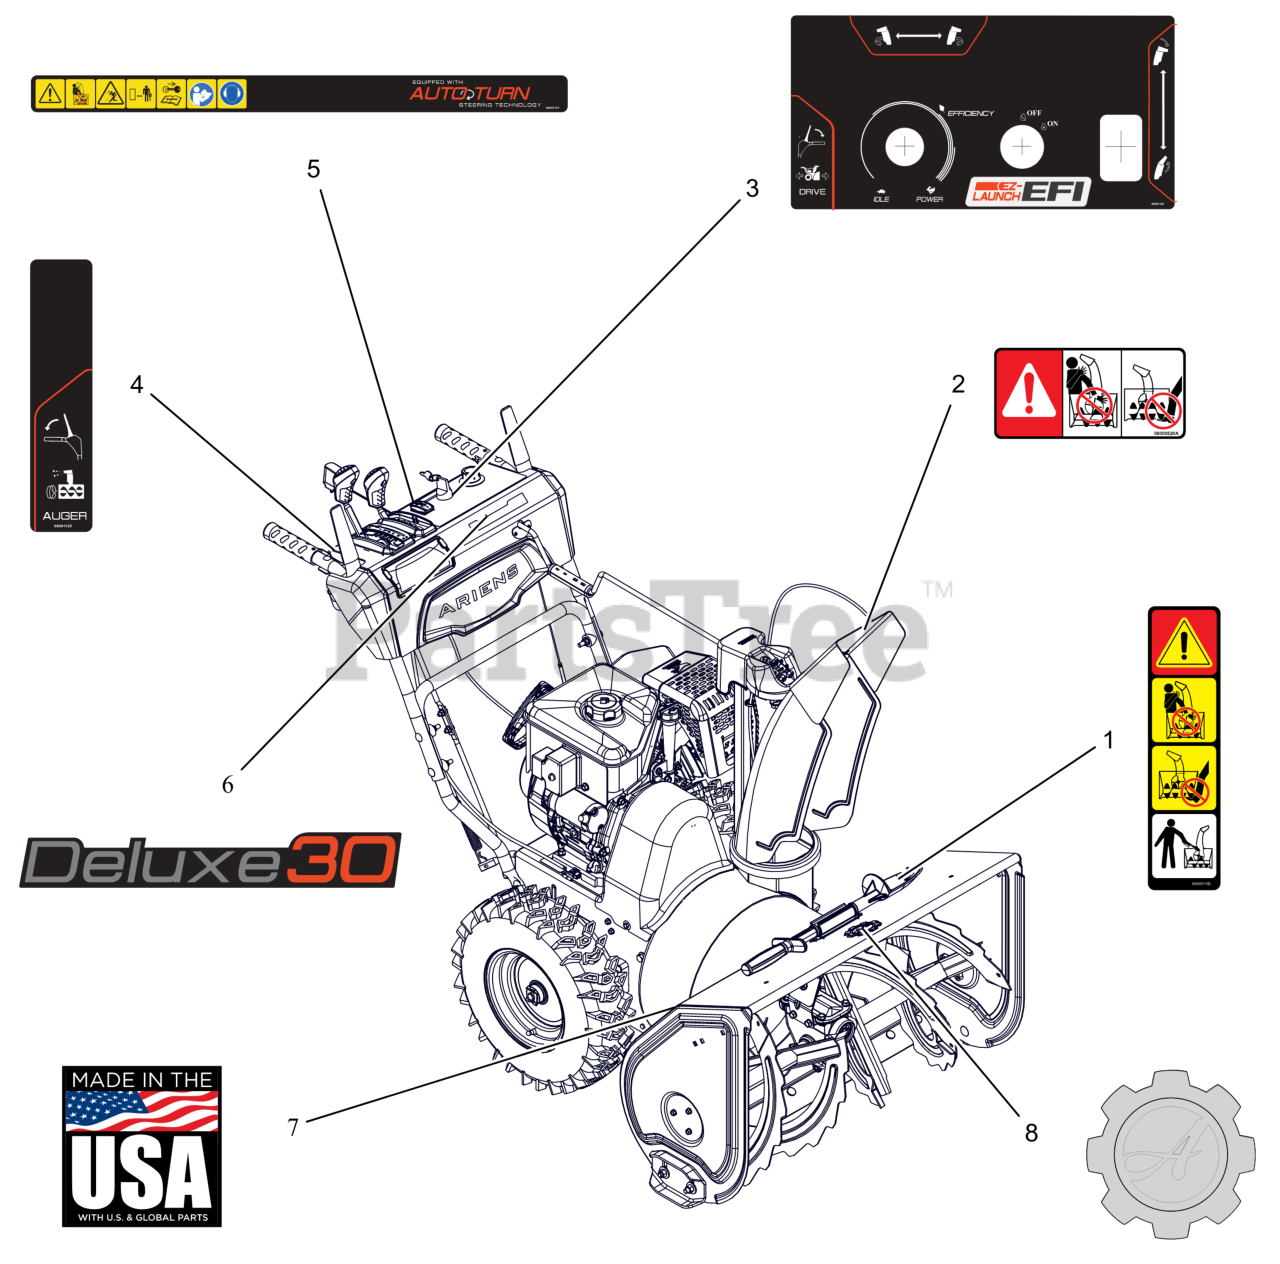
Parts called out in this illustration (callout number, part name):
1	DECAL, DANGER - ROTATING PARTS
2	DECAL, DANGER
3	DECAL, CONTROL - ID EFI W/GEL
4	DECAL,CONTROL-RH CONTROL
5	DECAL,DASH - SAFETY/EFI
6	DECAL, DASH - DELUXE 30
7	DECAL, MADE IN USA
8	DECAL, ARIENS-GEAR BADGE -THK
